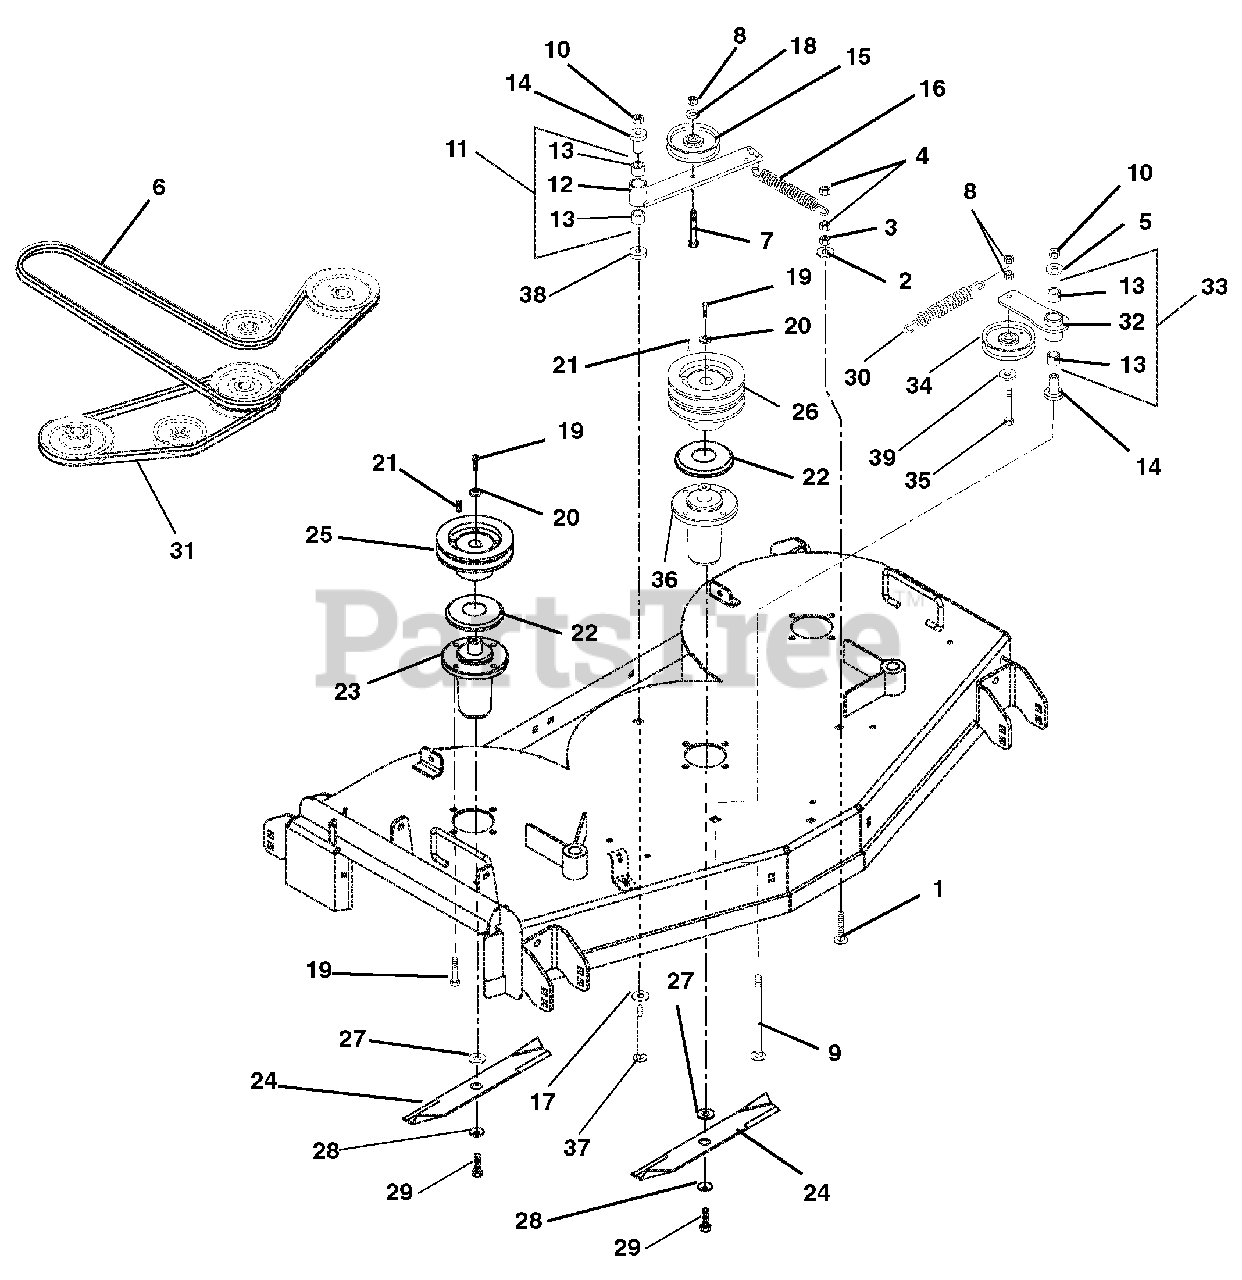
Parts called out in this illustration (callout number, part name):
1	@BLT-RDHDSQNK .38-16X1.50 G5YZ
2	@WSHR-LK .38X.094 REG YWZC
3	@NUT-HEX .38-16 YWZC
4	@NUT-LK-CTR .38-16 YWZC
5	WSHR-FL-STL .531X1.250X.10 YWZ
6	V-BELT, HB-WRAPPED
7	@BLT-RDHDSQNK .38-16X3.00 G5YZ
8	@NUT-LK-CTR .38-16 YWZC
9	@BLT-RHDSSQNK .50-13X3.50 G5YZ
10	@NUT-LK-CTR .50-13 YWZC
11	ASSEMBLY - IDLER PIVOT ARM
12	WMT - IDLER PIVOT ARM
13	BRG, 1.00 X 1.12 X .75
14	BEARING, PEDESTAL
15	IDLER-FLAT 4.00X.38 (2.00 W)
16	SPRING, EXTENSION
17	WSHR-FL-STL.755X1.375X.062YWZC
18	SEAL, IDLER BEARING
19	BLT-HEX .38-16X1.0 GR8 YZ EP30
20	WSHR,FLT STL.406X1.50X.245YWZC
21	KEY, SQ .25X.25X1.00 RC 40-50
22	SLINGER, DUST
23	ASM,MAINT FREE SPINDLE
24	BLADE, MULCH 16.25
25	WELDMENT, SPINDLE SHEAVE 5.00
26	SHEAVE, DOUBLE (5.25")
27	WSHR-FLT .640X1.75X.250
28	WSHR-BLVL .669X1.535X.138
29	BLT-HEX .62-18X1.75 GR8 YWZC
30	SPRING, EXTENSION
31	V-BELT, 5L-RAW EDGE
32	WMT, IDLER PIVOT ARM
33	ASM, IDLER PIVOT ARM
34	V-IDLER, 4.00X.38
35	@BLT-HEX .38-16X2.25 GR5 YWZC
36	ASM,MAINT FREE SPINDLE
37	@BLT-RDHDSQNK .50-13X3.75 G5YZ
38	WSHR-FL-STL .515X1.625X.250 YZ
39	@WSHR-FL-STL.406X.812X.065 YWZ
